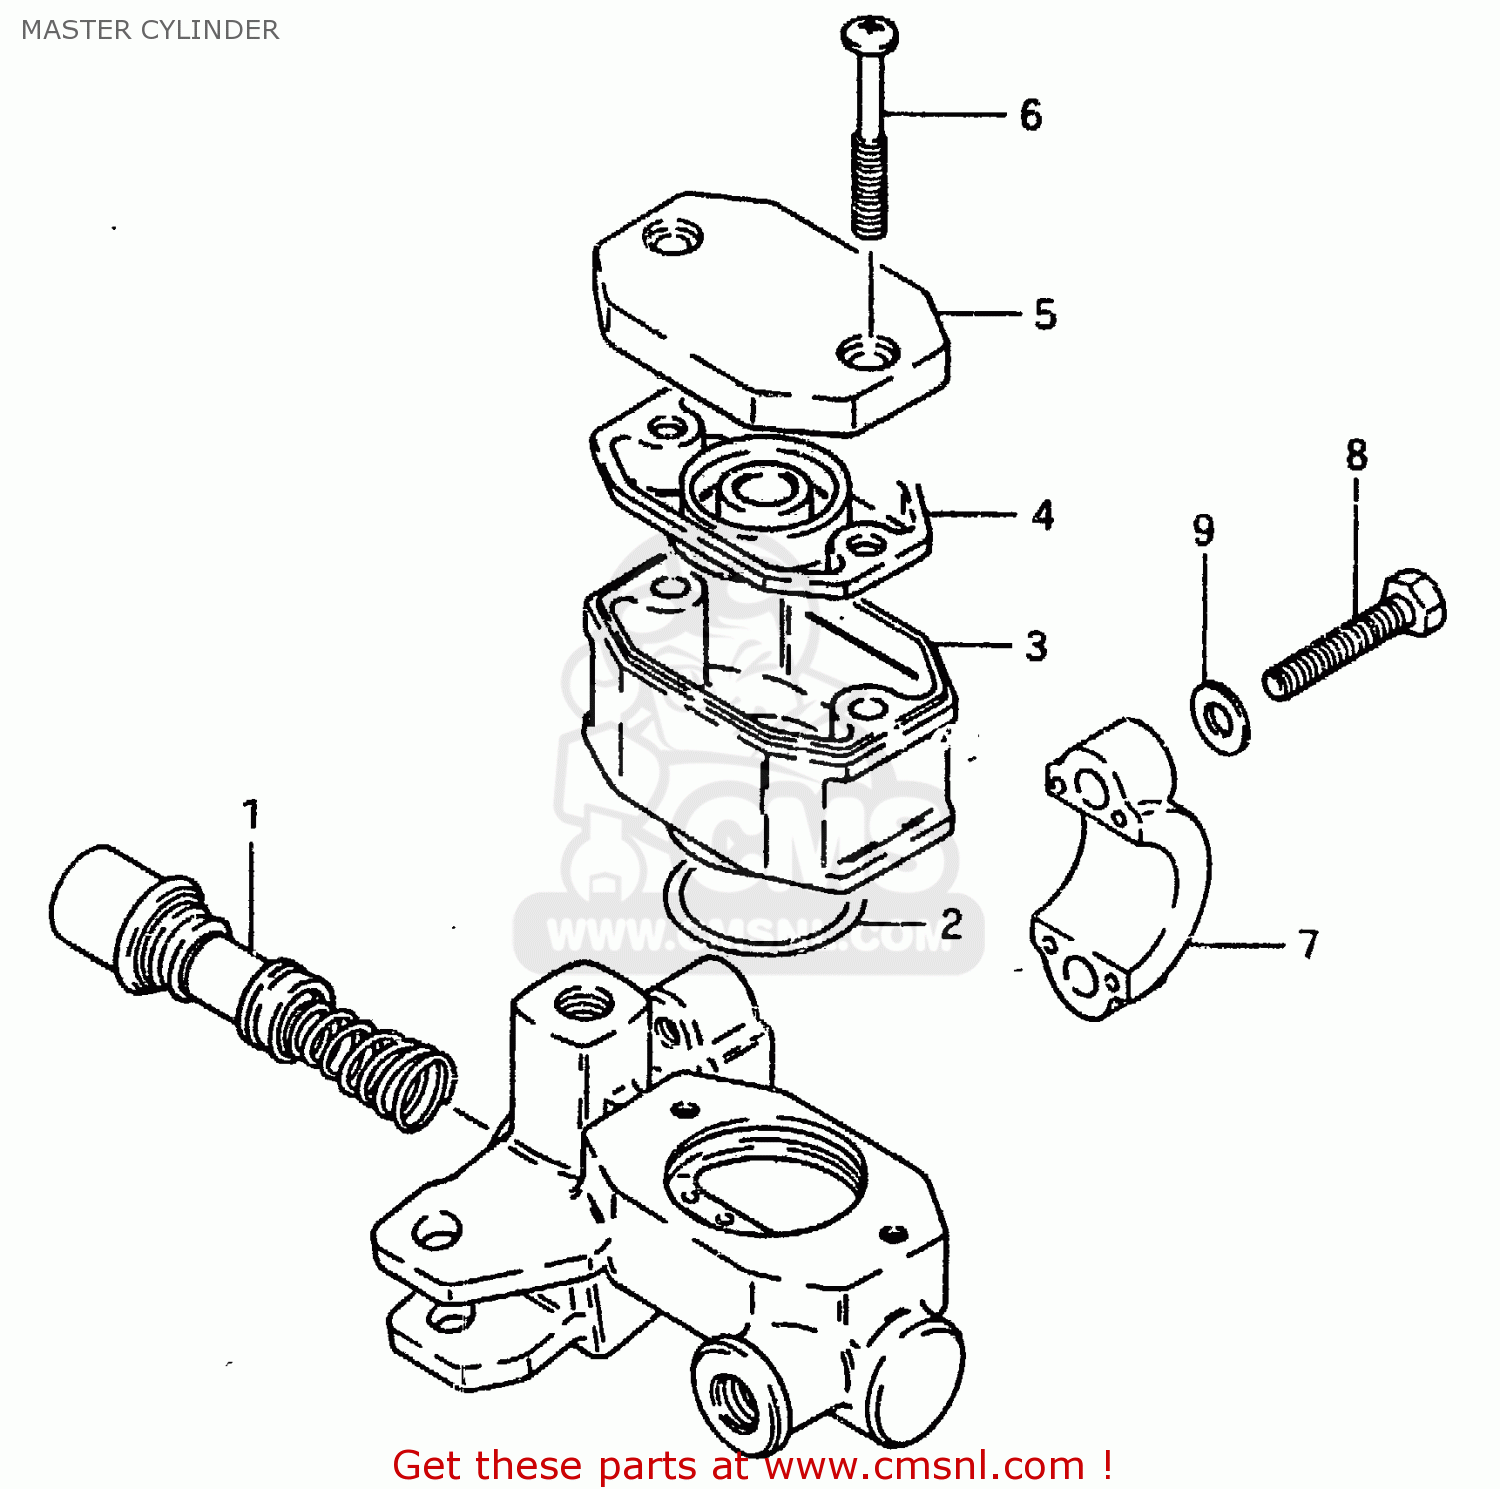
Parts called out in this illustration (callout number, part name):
1	PISTON & CUP SET
2	O RING
3	RESERVOIR
4	DIAPHRAGM
5	CAP,RESERVOIR
6	SCREW
7	HOLDER
8	BOLT
9	WASHER
